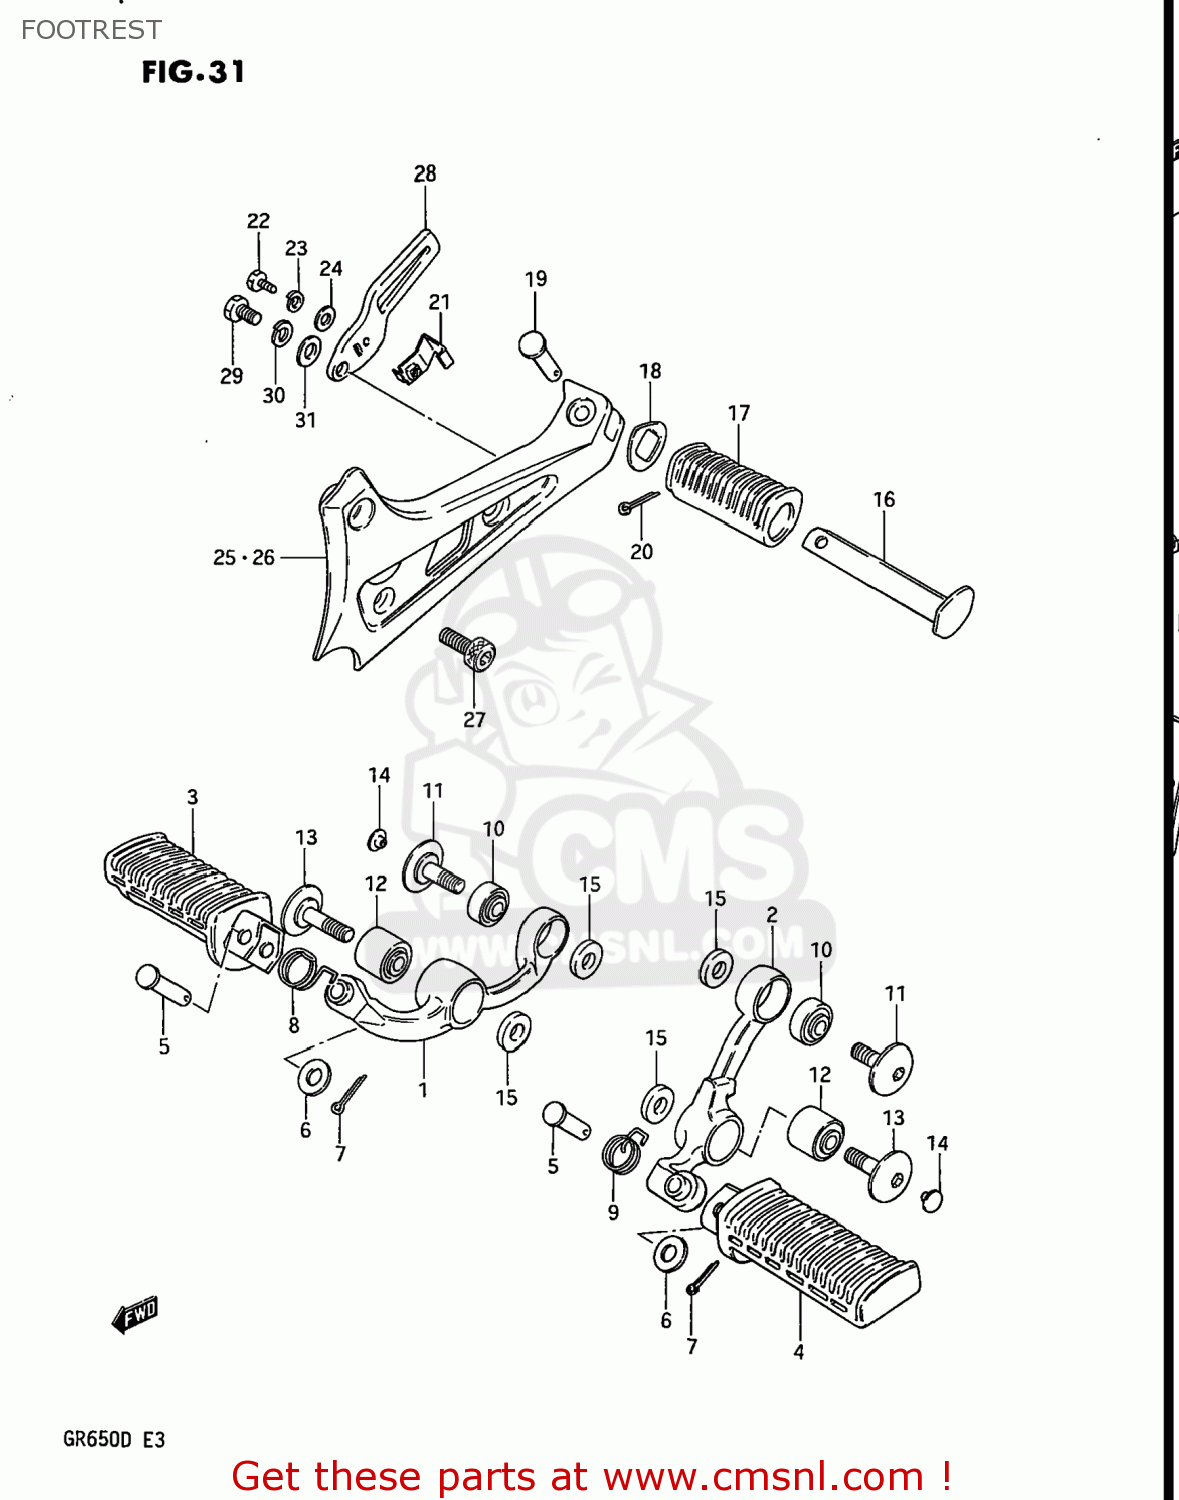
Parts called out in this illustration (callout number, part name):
1	BAR,FRONT FOOTREST,RIGHT
2	BAR,FRONT FOOTREST,LEFT
3	RUBBER,FOOTREST
4	FOOTREST
5	PIN
6	WASHER
7	PIN 20X20
8	SPRING
9	SPRING
10	BUSHING
11	BOLT 10X30
12	BUSHING
13	BOLT
14	CAP
15	WASHER (10.1X22X3.2)
16	BAR,REAR FOOTREST,LEFT
17	RUBBER,PILLION FOOTREST
18	WASHER,REAR FOOTREST RUBBER
19	PIN
20	PIN 20X20
21	COVER, PILLION FOOTREST
22	BOLT, UPPER
23	LOCK WASHER
24	WASHER
25	BRACKET,MUFFLER,RIGHT
26	BRACKET,MUFFLER,LEFT
27	BOLT
28	PLATE,FOOT GUIDE
29	BOLT
30	LOCK WASHER
31	WASHER
